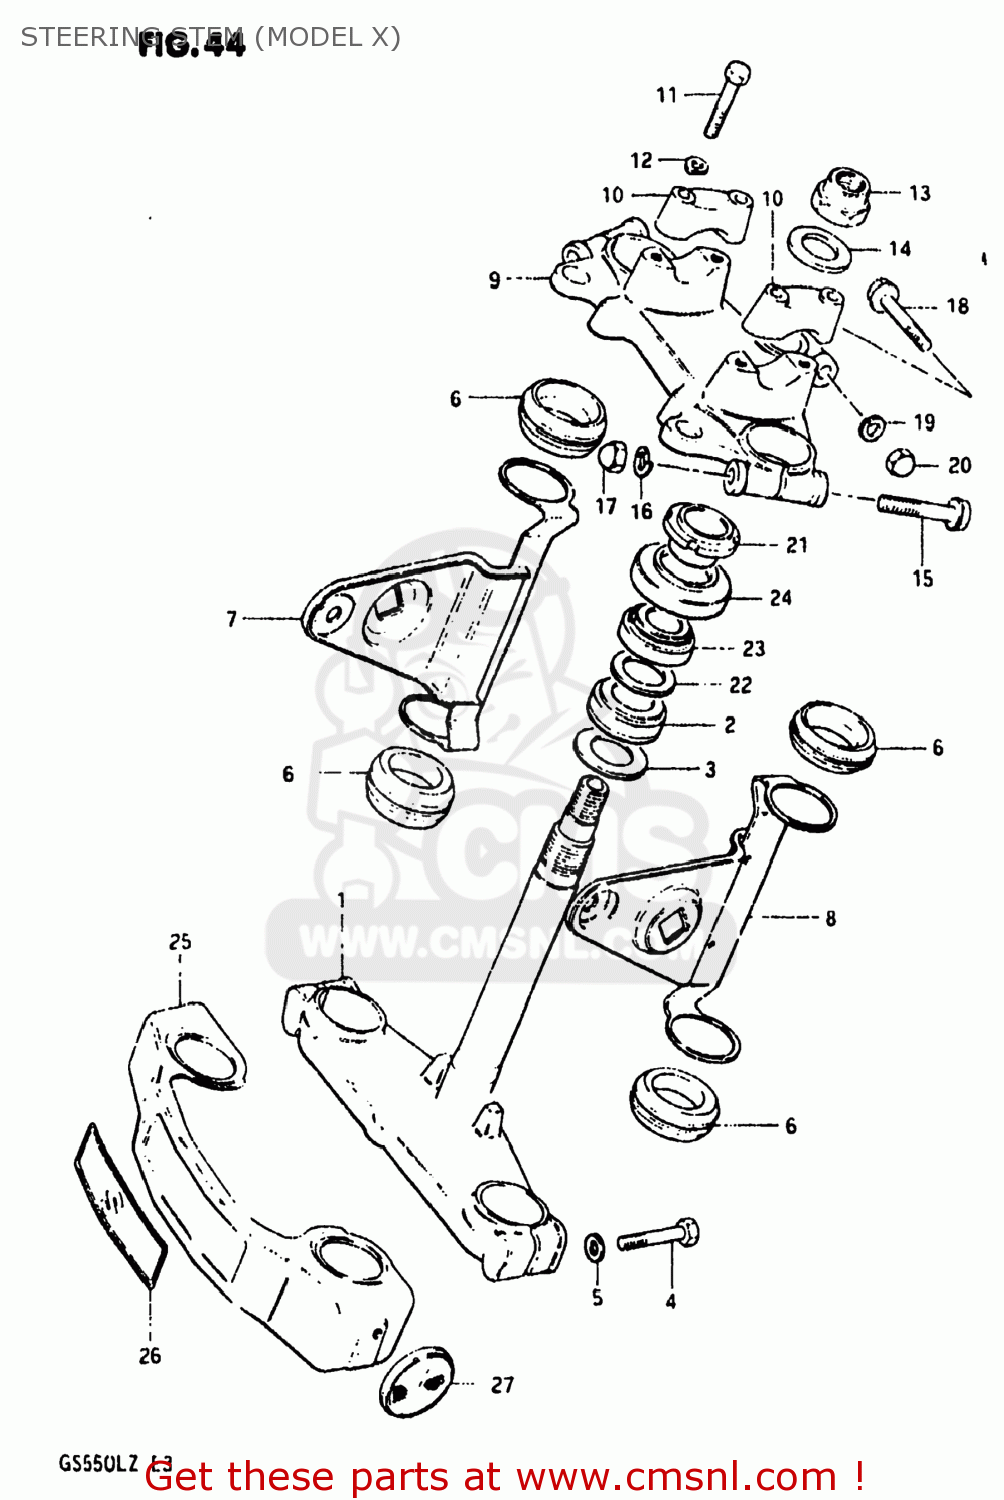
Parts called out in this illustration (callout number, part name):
1	STEM,STEERING
2	BEARING
3	WASHER,THRUST
4	BOLT 8X45
5	WASHER,LOCK,8.
6	CUSHION,HEADLAMP BRACKET
7	BRACKET,HEADLAMP,RIGHT
8	BRACKET,HEADLAMP,LEFT
9	HEAD,STEERING STEM
10	HOLDER,HANDLE UPR
11	BOLT
12	LOCK WASHER
13	NUT,FR FORK UPR BRACKET
14	WASHER
15	BOLT 10X55
16	LOCK WASHER
17	NUT
18	BOLT
19	LOCK WASHER
20	NUT
21	NUT,STEERING STEM
22	WASHER(18.5X24X1)
23	TAPER,ROLLER BEARING
24	DUST SEAL,STEERING,UPPER
25	COVER,FRONT FORK
26	EMBLEM,FR FORK COVER
27	REFLEX REFLECTOR,RR
